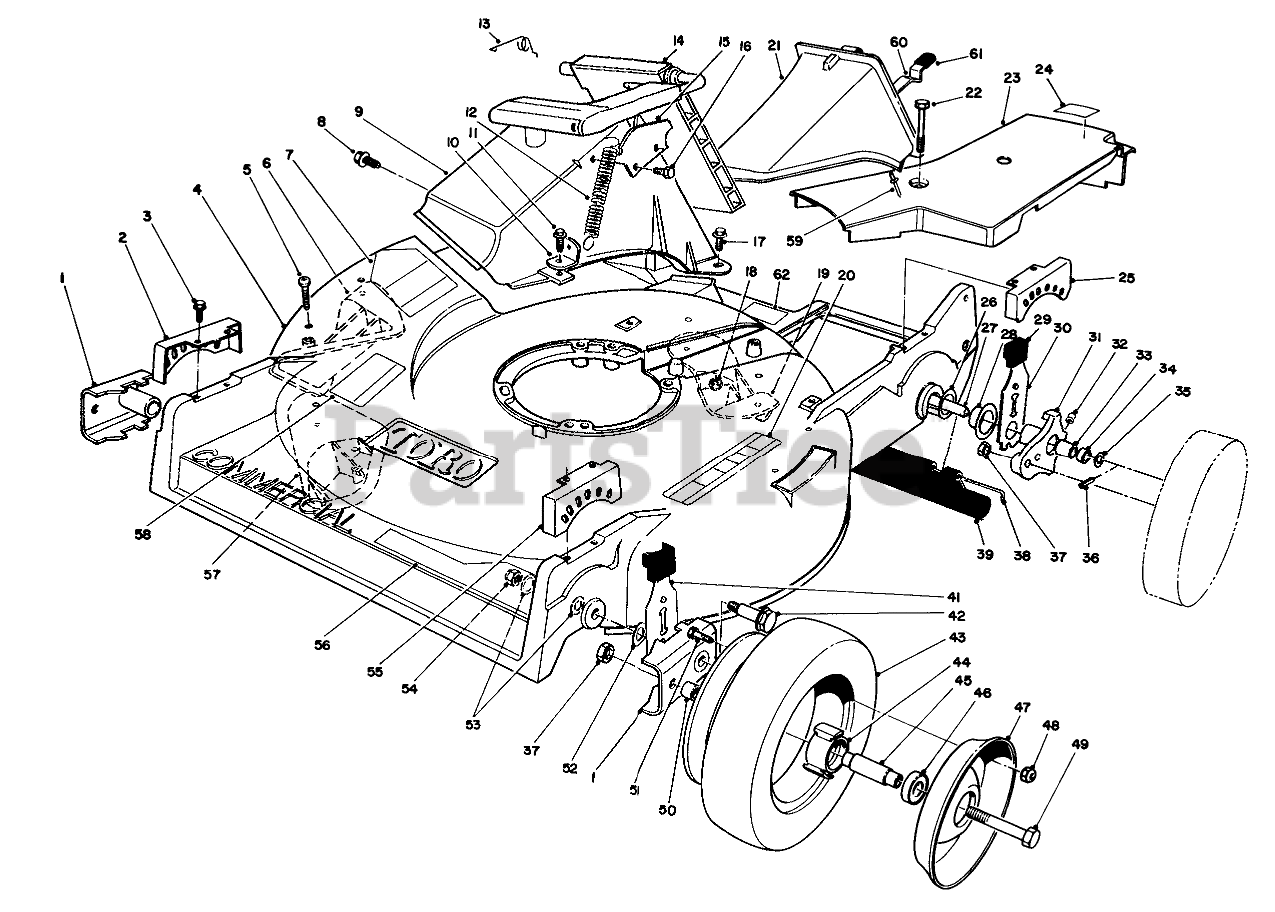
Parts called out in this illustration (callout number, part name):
1	ARM-PIVOT, FRONT
2	QUADRANT-FRONT, RH
3	SCREW-HWHTF
4	Housing (Incl. Ref. #5-7, 19, 20, 57, 58 & 62)
5	SCREW-PPH
6	KICKER-RH
7	DECAL-DANGER
8	SCREW AND WASHER ASM
9	DISCHARGE TUNNEL
10	BRACKET-SPRING
11	SCREW-HWH
12	SPRING-DOOR
13	RETAINER-DOOR
14	DOOR ASSEMBLY
15	DOOR LATCH PLATE
16	SCREW-PLASTITE
17	SCREW-HH
18	NUT-LOCK, NI
19	KICKER-REAR
20	DECAL-INSTRUCTION, SAFETY
21	DISCHARGE PLUG ASM
22	SCREW-HHFTF
23	COVER-BELT
24	LABEL-GREASE, HP
25	QUADRANT-REAR, LH
26	WASHER
27	SHAFT-AXLE, REAR
28	CAP-END
29	KNOB-ARM
30	REAR SPRING ARM ASM
31	Arm-Pivot (Incl. Ref. #32-34)
32	FITTING-GREASE
33	BUSHING
34	BUSHING
35	WASHER-PLAIN
36	PIN-SPIROL
37	NUT-LOCK, CONE
38	ROD-SHIELD
39	SHIELD-TRAILING
41	FRONT SPRING ARM ASM
42	BOLT-WHEEL
44	HUB-BEARING
45	SPACER-BEARING
46	BEARING-WHEEL
47	Wheel-Half
48	NUT-LOCK, NI
49	SCREW-HH
50	SPACER-WHEEL
51	SCREW-HH
52	WASHER-THRUST
53	WASHER
54	NUT-LOCK
55	QUADRANT-FRONT, LH
56	DECAL - RECYCLER
57	KICKER-FRONT
58	DECAL - DANGER, COVERS
59	RIVET-HEAD, FLAT
60	LATCH-PLUG, DISCHARGE
61	GRIP-LATCH
62	DECAL-WARNING
